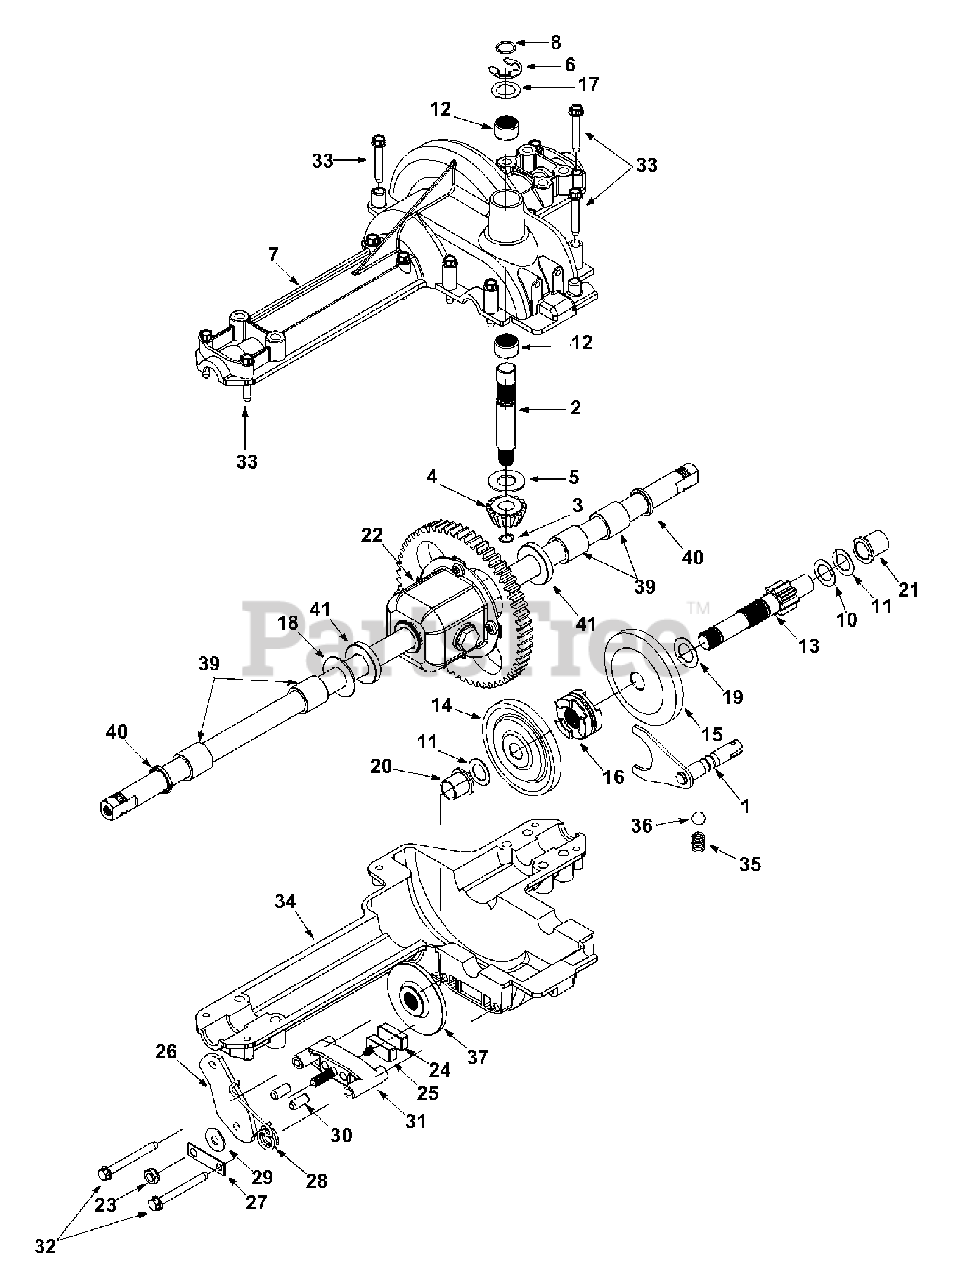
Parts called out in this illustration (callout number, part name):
1	Shift Fork Assembly
2	Input Shaft
3	Retaining Ring
4	Pinion Input 14T
5	Needle Brg. 5/8" I.D. x 1" O.D.
6	"E" Ring
7	Upper Housing
8	Wire RIng
10	Thrust Wash. 5/8" I.D. x 1" O.D. x .025" Thk.
11	Fl-Wash. 5/8" I.D. x 1" O.D. x .020 Thd.
12	Needle Brg. 5/8" I.D. x 1/2" Lg.
13	Drive Shaft - R.H. Brake
14	Bevel Gear 42T Small I.D.
15	Bevel Gear 42T Large I.D.
16	Clutch Collar
17	Fl-Wash. 5/8" I.D. x 1" O.D. x .020" Thk.
18	Fl-Wash. .76" I.D. x 1.5" O.D. x .010" Thk.
19	Thrust Washer
20	Flange Brg. 5/8" I.D. x 3/4" Lg.
21	Flange Brg. 5/8" I.D. x 15/16" Lg.
22	Differential Ass'y
23	Hex Nut 5/16-24 Thd.
24	Brake Puck
25	Puck Plate
26	Actuating Arm
27	Anti-Rotation Brkt.
28	R.H. Brake Spring
29	Fl-Wash. .344 I.D. x .875" O.D.
30	Actuating Pin 5/16" Dia.
31	Brake Yoke
32	Hex Wash. Hd. Self-Tap Scr. 1/4-20
33	Hex Tap Scr. 1/4-20 x 1.625" Lg.
34	Lower Housing
35	Spring Detent
36	Ball Detent .250" DIa.
37	Brake Disc.
39	Sleeve Bearing 3/4" I.D. 1.0" Lg.
40	Oil Sleeve 3/4" I.D.
41	Fl-Wash. .760" I.D. x 1.5" O.D.
